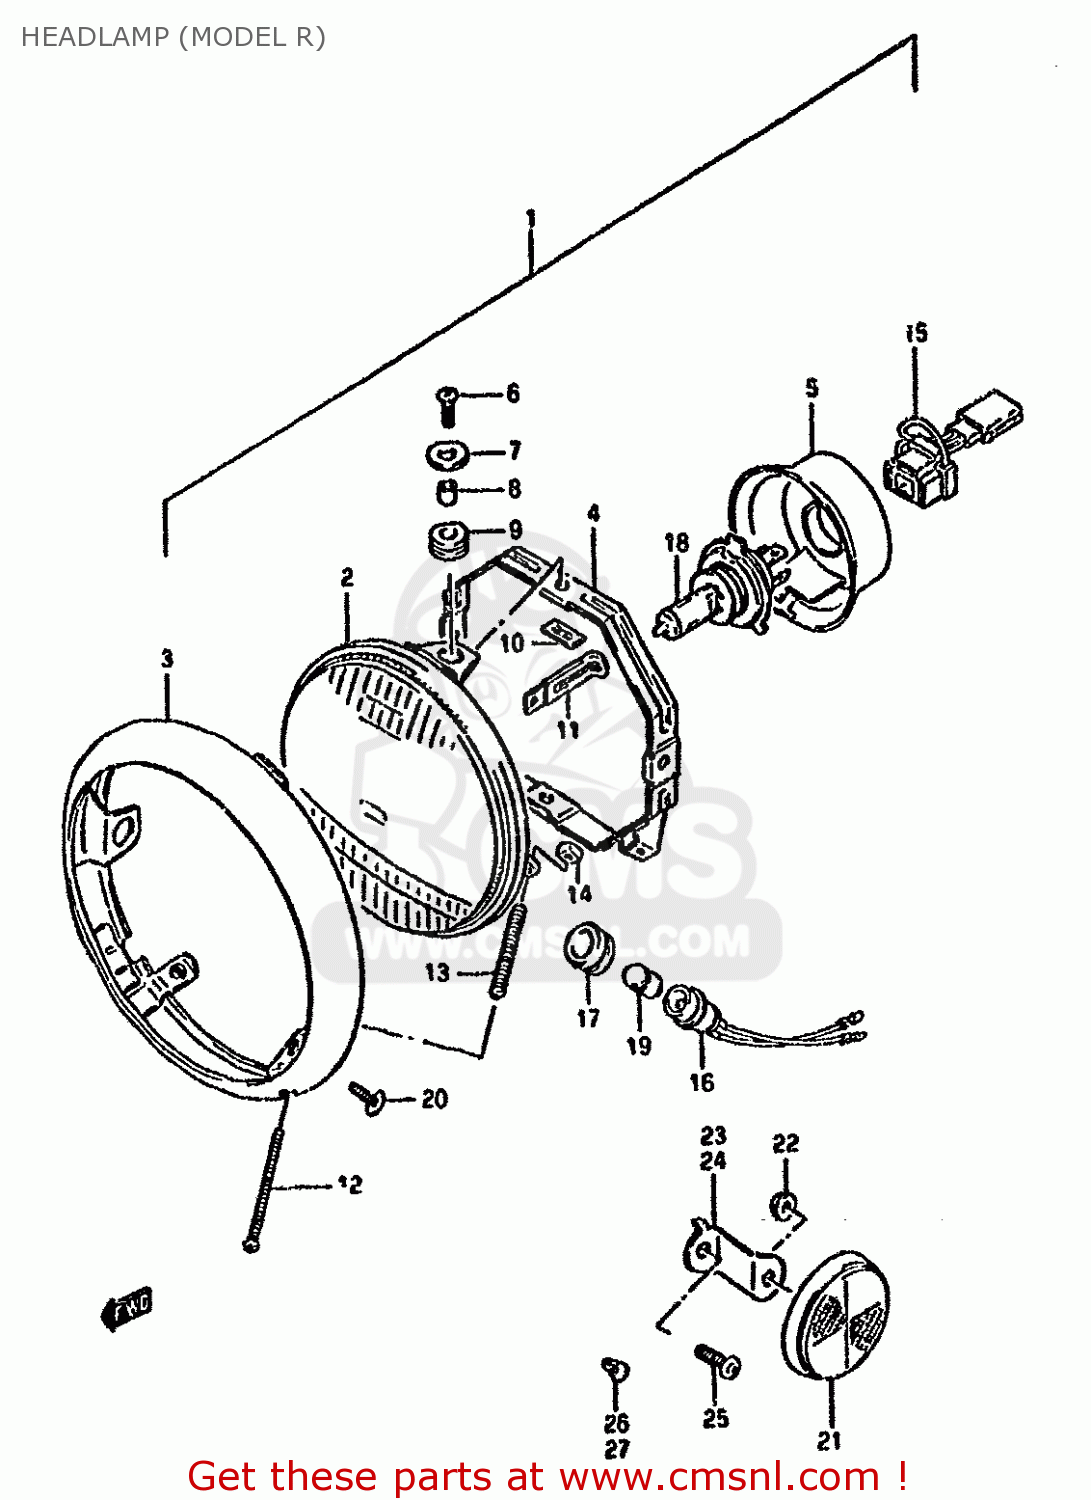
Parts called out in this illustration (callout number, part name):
1	HEADLAMP ASSY
2	UNIT
3	RIM
4	RING,MOUNTING
5	COVER,SOCKET
6	SCREW
7	WASHER
8	SPACER
9	CUSHION
10	NUT
11	CLAMP
12	SCREW,HEADLAMP ADJUST
13	SPRING
14	NUT
15	SOCKET
16	SOCKET
17	JOINT,RUBBER
18	BULB(12V60/55W,H4)
19	BULB(12V3.4W,STANLEY,A72A)
20	SCREW
21	REFLECTOR,REFLEX FR
22	NUT
23	BRACKET,FRONT SIDE RH
24	BRACKET,FRONT SIDE RH
25	SCREW
26	CLIP
27	CLIP
28	CLIP
